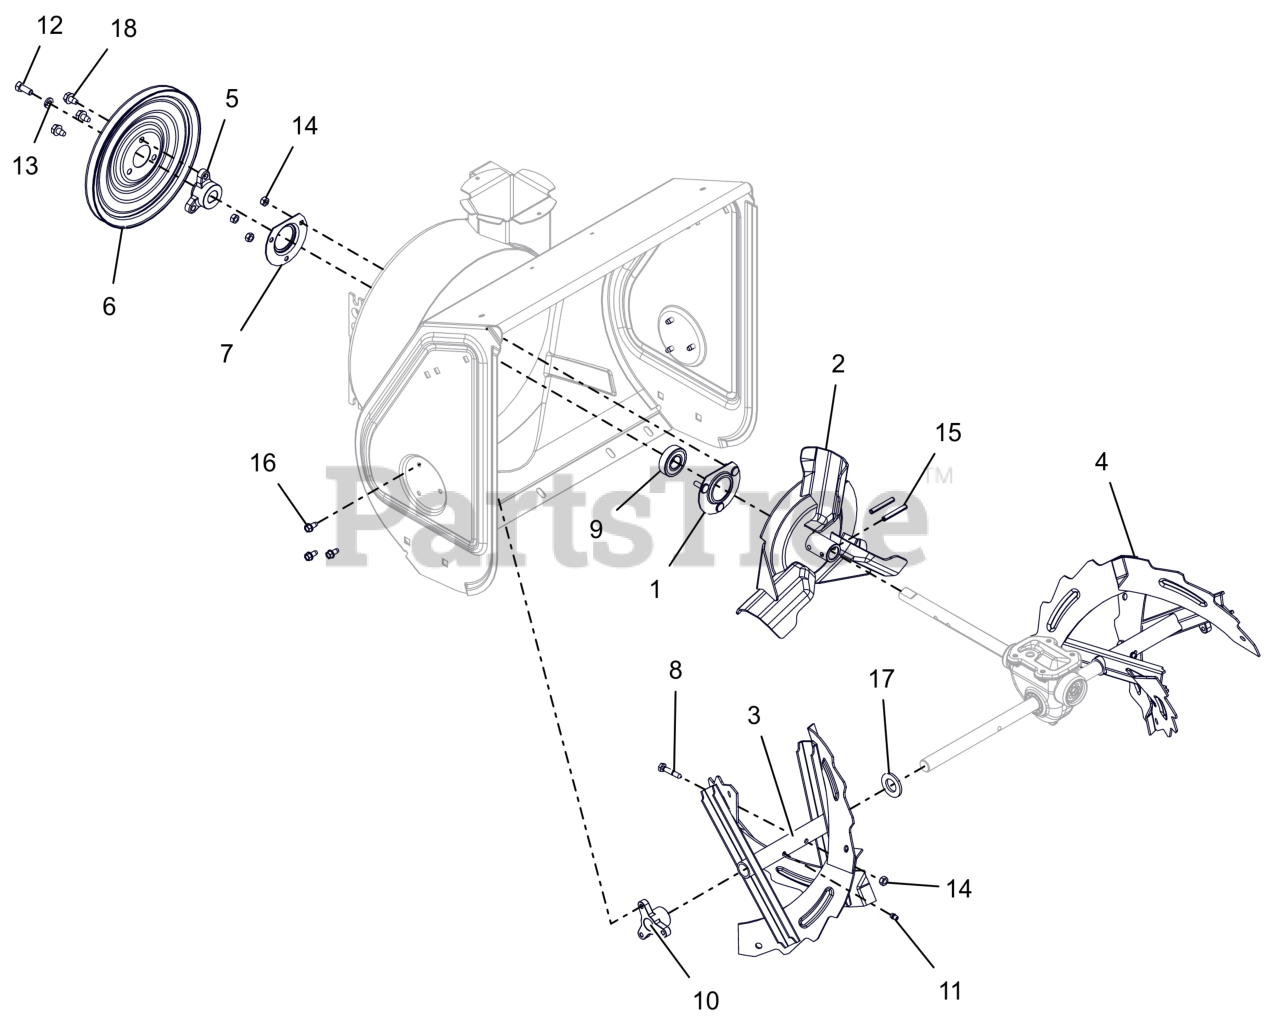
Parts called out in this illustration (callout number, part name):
1	BEARING FLANGE
2	IMPELLER, COMPACT 12" 3-BLADE
3	AUGER, 20" RH, BLK SERR W/ZERK
4	AUGER, LH 20", BLK SERR W/ZERK
5	PULLEY HUB, BOLT-ON D-BORE .75
6	PULLEY,SPIN FORM SINGLE GROOVE
7	BEARING FLANGE
8	SHEAR BOLT WITH NUT
9	BRG-BALL .750X1.750X.50
10	BUSHING, RAKE SHAFT .75"
11	ZERK,FITTING .25X.125 DRIVE IN
12	BLT, HEX .31-24X.750 G5 ZCC
13	WSHR, LK-HVY .312X.097 ZCC
14	NUT,LK-CTR .25-20 GA ZCC
15	PIN-ROLL .250X1.75
16	SCR-TAP .25-20X.50 HWH ZCC
17	WSHR, FLT .812X1.469X.134 ZCC
18	SCR,TAP .312-18X.50 HWH TR ZCC
